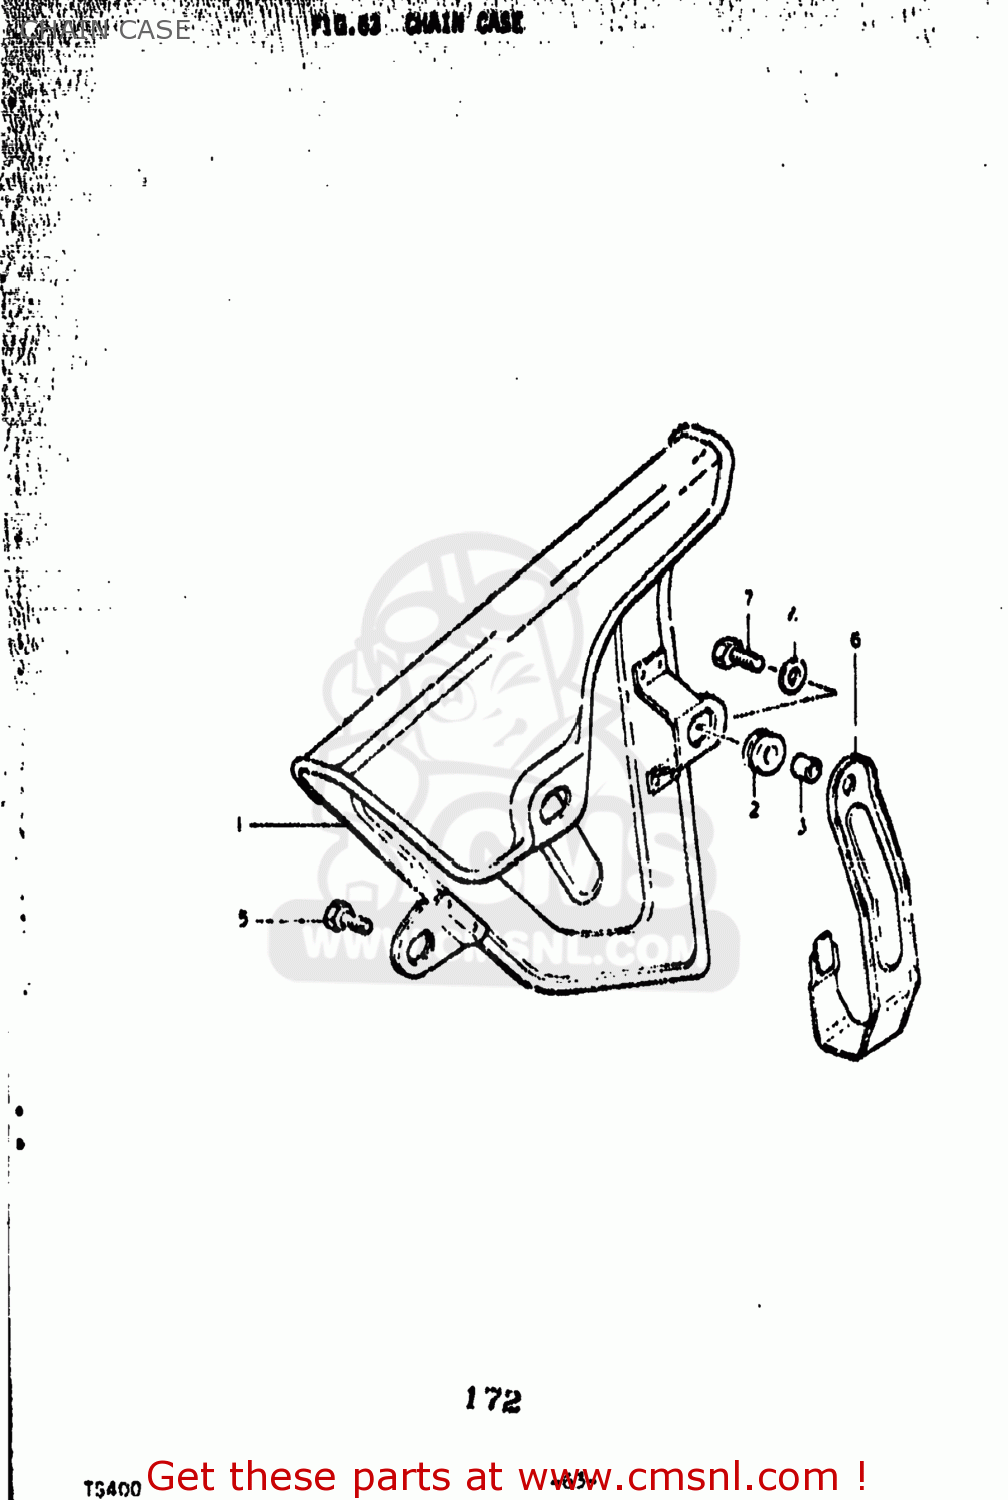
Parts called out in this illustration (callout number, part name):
1	CASE,CHAIN
2	CUSHION
3	SPACER (7X9X7)
4	WASHER (6.5X20X1.2)
5	BOLT
6	GUIDE,DRIVE CHAIN
7	SCREW(6X14)
